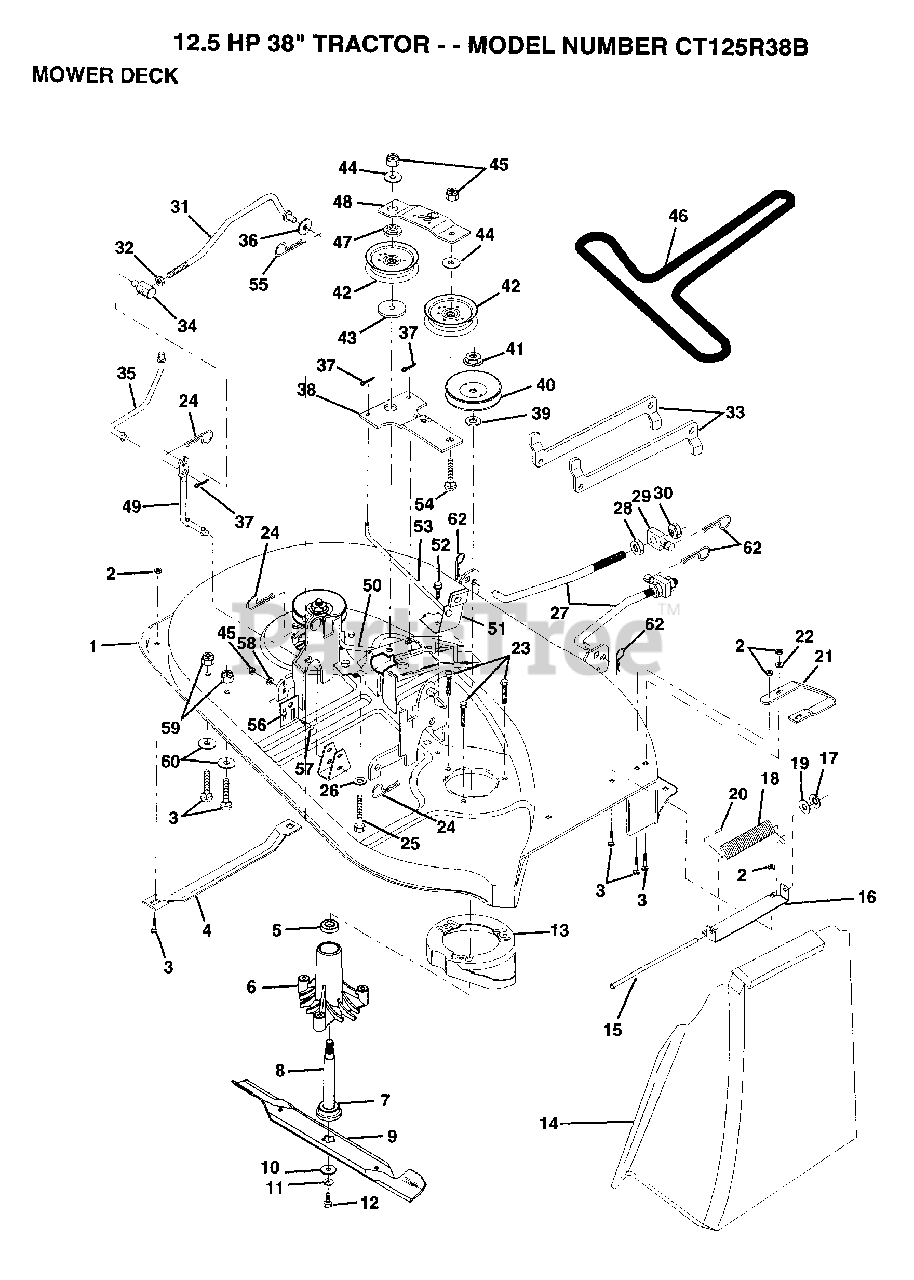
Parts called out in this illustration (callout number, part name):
3	BOLT
4	RUNNER-LH M
5	BEARING
6	HSG ASM MANDREL
7	BEARING.BALL
9	"BLADE.38"" HIPERF"
10	WASHER BLADE
12	BLADE BOLT
14	DEFLECTOR-SHLD T
15	ROD-HINGE T
16	BRKT DEFLECTOR
17	NUT PUSH M
19	WASHER
20	CAP-SLEEVE LT
21	RUNNER RH
22	WASHER M
25	BOLT
26	WASHER GT
27	"LINK ASM.,FRONT"
28	NUT
29	TRUNION
30	NUT.LK.W/WSH.1/2.
31	CLUTCH ROD PRI
32	NUT
33	SUSP ARM REAR
34	TRUNNION
35	CLUTCH ROD SEC
36	WASHER
38	IDLER ARM ASSY
39	WASHER
42	FLAT IDLER PULLEY
43	SPACER RETAINER
44	WASHER GT
46	BELT-V.88.12.MW
47	RETAINER SPACER
48	IDLER ARM STIFF
49	PIVOT ROD
50	BRAKE ROD LH
51	BRAKE ASM
52	SCREW
53	BRAKE ROD RH
54	BOLT
55	RETAINER M
56	PLATE ADJ LINK LH
57	BOLT
58	WASHER T
59	NUT
60	WASHER.34X.68X16
61	BOLT
62	RETAINER.SPRING
